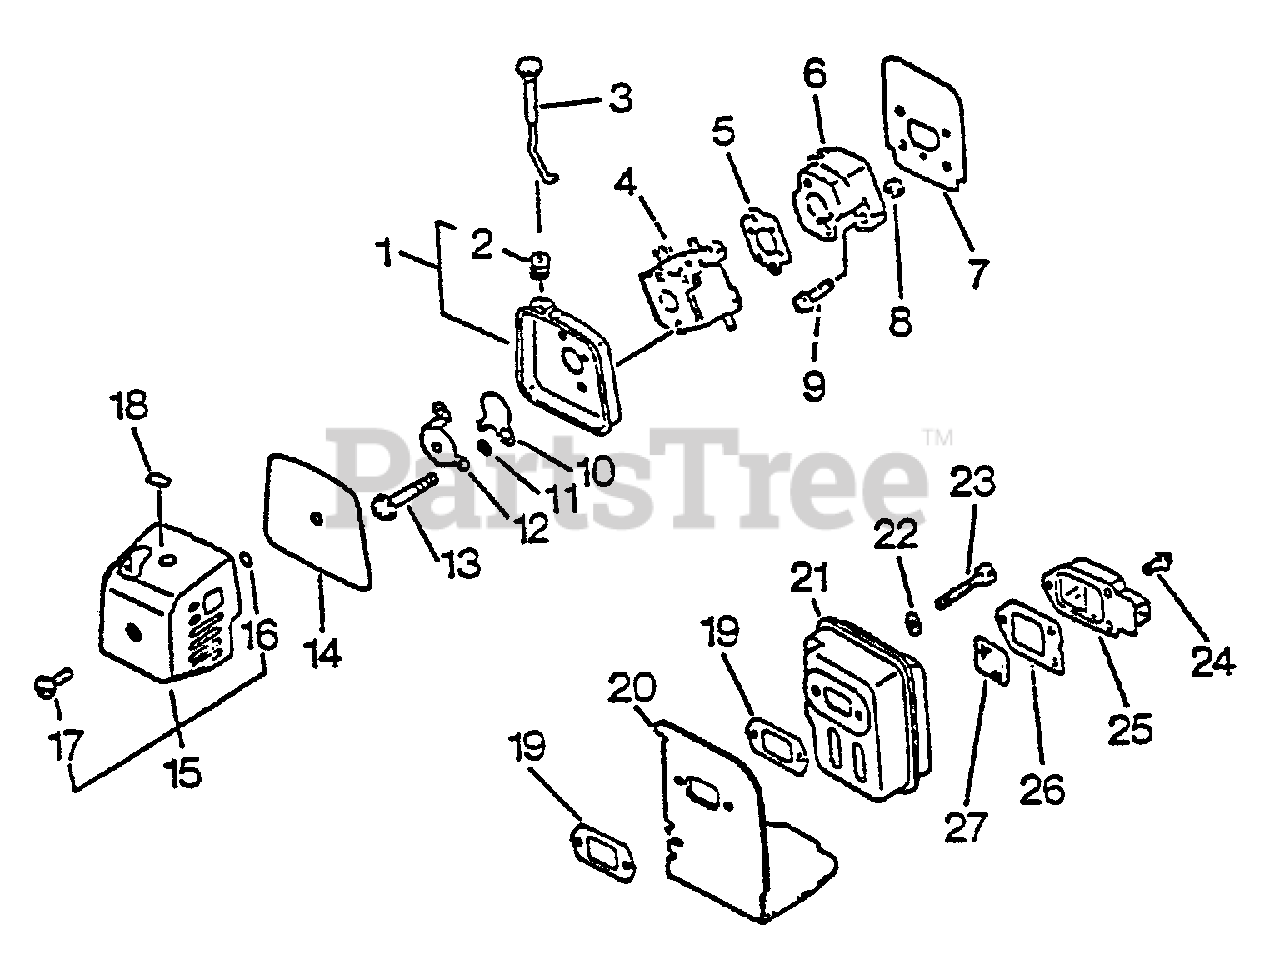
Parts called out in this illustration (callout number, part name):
1	CASE, AIR FILTER
3	ROD, CHOKE
4	CARBURETOR C1U-K12
5	GASKET, INTAKE
6	INSULATOR, INTAKE
7	SHIELD, INTAKE
9	SCREW - 5X20
10	SHUTTER, CHOKE
11	WASHER - 5
12	BRACKET, AIR CLEANER
13	SCREW - 5X57
14	FILTER, AIR
15	AIR FILTER COVER ASSY
16	O-RING - 4
18	LABEL - CHOKE
19	GASKET, EXHAUST
20	COVER, EXHAUST
21	MUFFLER ASSY
22	WASHER - 5
23	SCREW - 5X55
24	SCREW - 4X10
25	GUIDE, EXHAUST - OUTER
26	GASKET, EXHAUST
27	SCREEN, SPARK ARRESTOR
